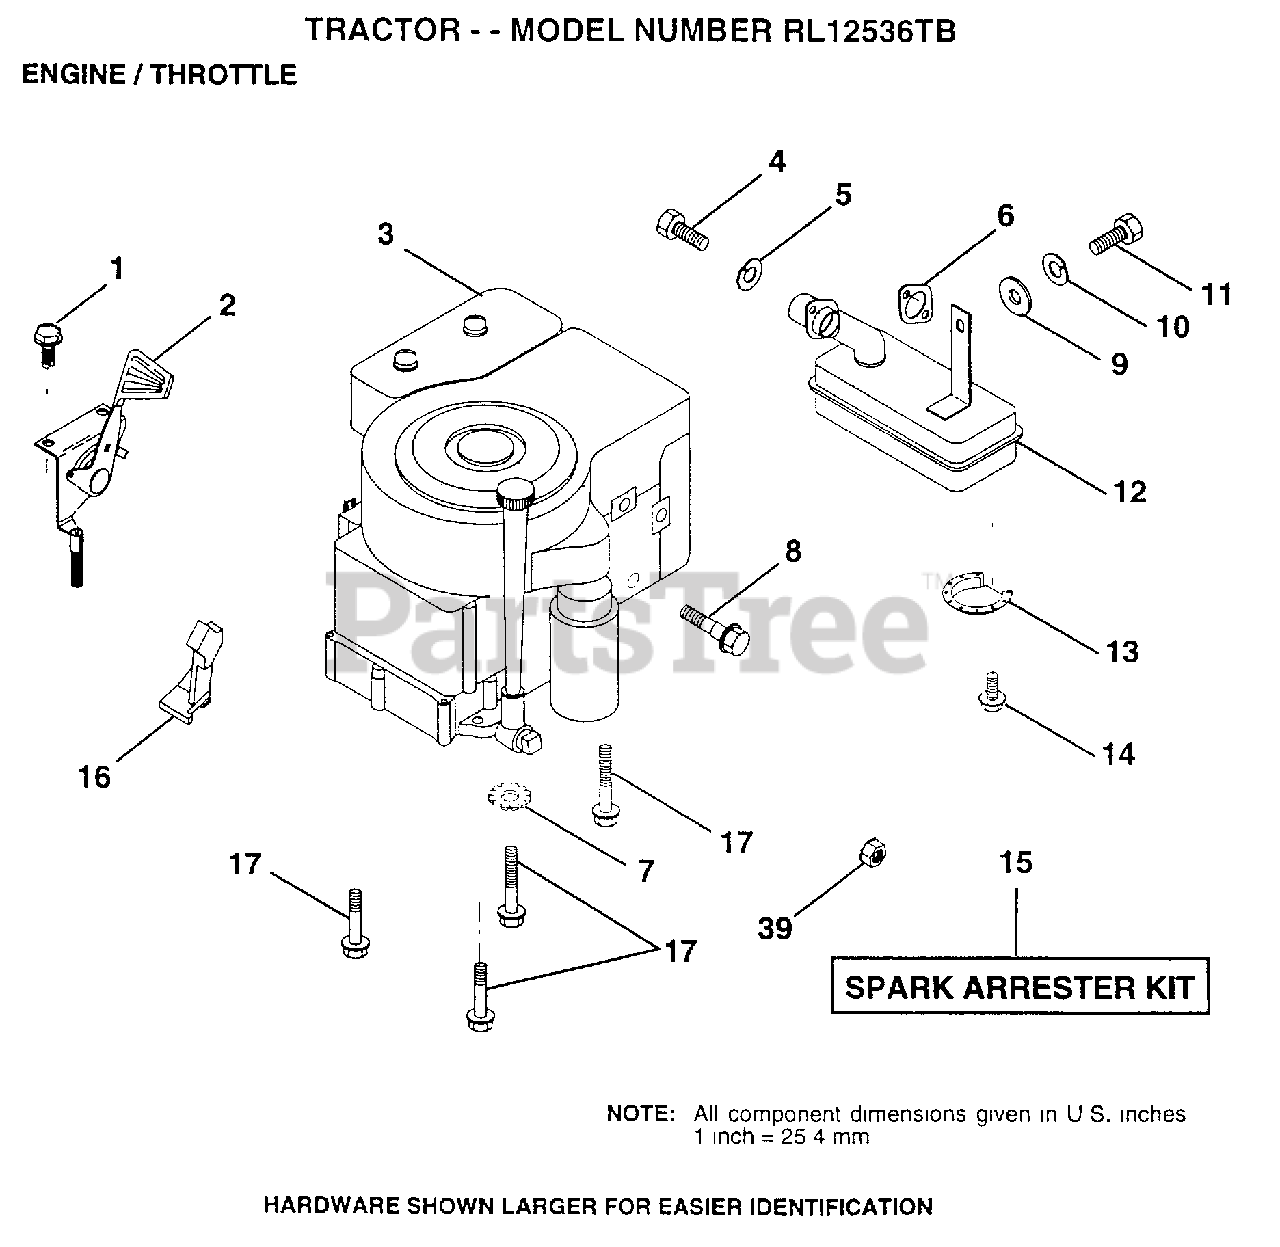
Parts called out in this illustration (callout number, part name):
1	SCREW.1/4-20X1/2
3	ENGINE B&S 12.5 HP
4	SCREW HEX HD CAP
5	LOCKWASHER
6	GASKET ENG 1 313 LD TIN PLATED
7	LOCKWASHER
8	SHOULDER BOLT ST
10	LOCKWASHER
11	BOLT LT
13	DEFLECTOR.222573
16	STOP.THROTTLE
17	SCREW LT
39	NUT
